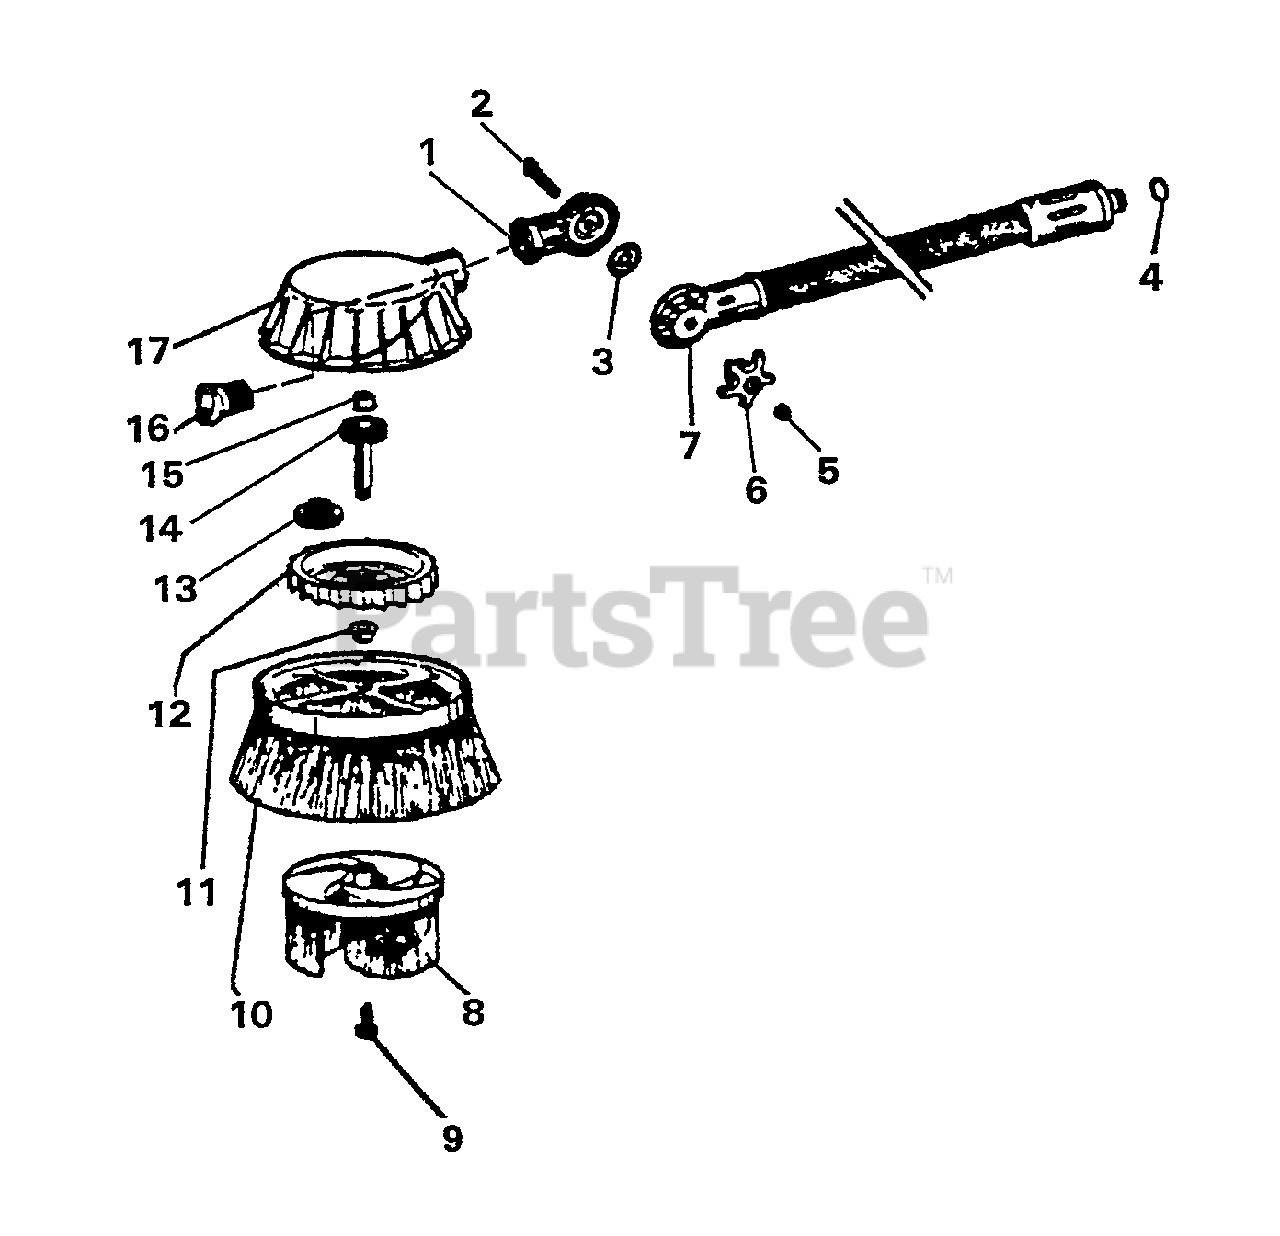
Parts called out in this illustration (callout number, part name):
1	CONNECTOR, ADJUSTABLE
2	SCREW M6×40
3	GASKET, CONNECTOR
4	O-RING
5	NUT - 6
6	KNOB, REGULATING
7	HAND GRIP, BRUSH
8	BRUSH, ROTATING
9	SCREW 6P×13
10	BRUSH, FIXED
11	BUSHING
12	TURBINE
13	GEAR
14	SHAFT, GEAR
15	BUSHING
16	NOZZLE, 3.85
17	COVER
